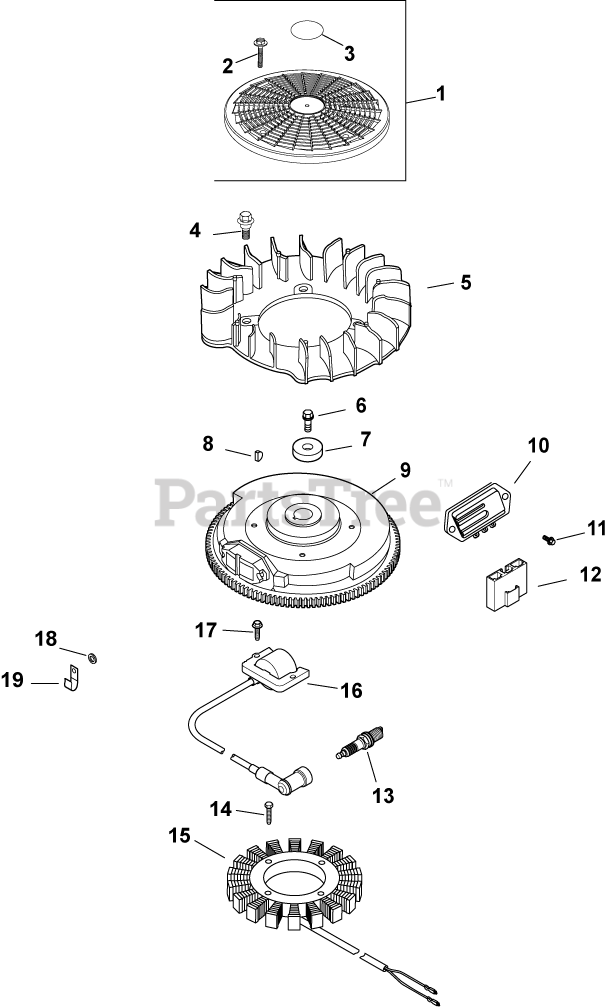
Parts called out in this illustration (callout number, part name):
1	KIT, GRASS SCREEN
2	SCREW, FLG SEMS M4X.7X25
3	DECAL, GRASS SCREEN USE 24 113 499-S
4	BOLT, SHOULDER
6	SCREW, FLG M10X1.5X45 - (#25086361S)
7	WASHER, FLAT 13/32"
8	KEY, 3/16" X 5/8"
10	REG/RECT-15 AMP (KM)-USE 41 403 10-S
11	SCREW, HEX FLANGE HI-LO
12	CONNECTOR, BODY (KM)-USE 25 155 41-S
13	PLUG, SPARK (STD)
14	SCREW, FLG THD FRM M5X.8X20-(#25086399S)
15	KIT, 15 / 20 AMP STATOR
16	KIT, MODULE IGNTN (CDI FIXED)
17	SCREW, M5X0.8X25 - (#25086402S)
18	WASHER, FLAT 1/4" (O.D. 1/2")
19	CLIP, CABLE
